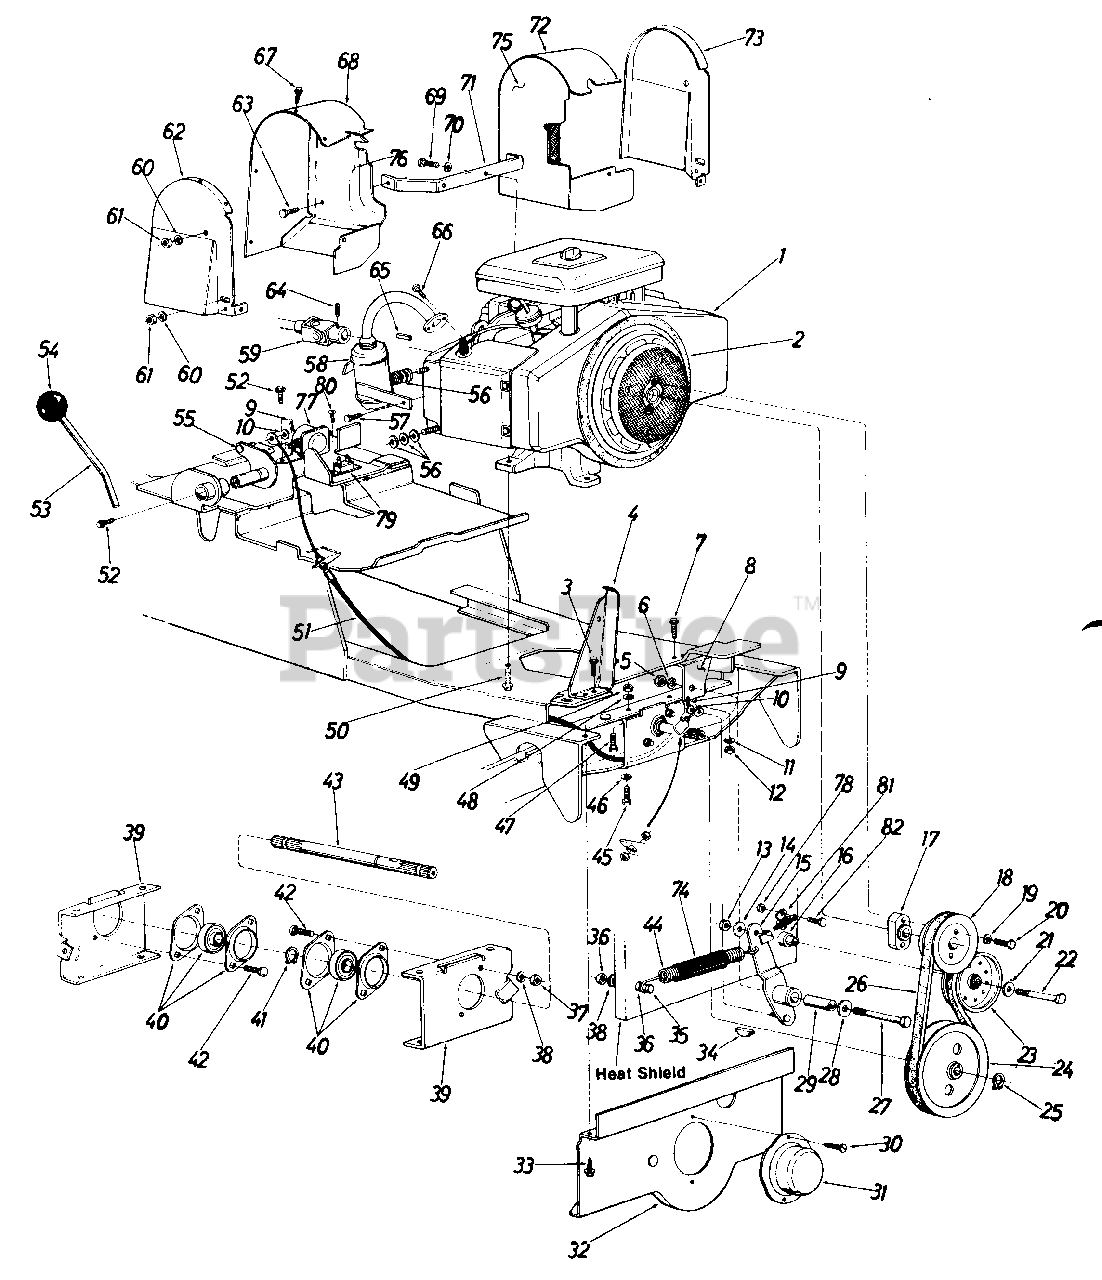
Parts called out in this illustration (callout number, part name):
1	Engine
2	Mylar Foam Strip
3	Hex Wash. Hd. Self-Tap Scr. 1/4-20 x .75" Lg.
6	L-Wash. 3/8" Scr.*
7	Hex Wash. Hd. Self-Tap Scr. 5/16-18 x .75" Lg.
10	Fl-Wash. .38" I.D x 1.25 O.D. x .10 Thk.
11	L-Wash. 3/8" Scr.
12	Hex Nut 3/8-16 Thd.
13	Hex Nut 3/8-16 Thd.*
14	Fl-Wash. .38 I.D. x 1.25" O.D. x .10 Thk.
17	Pulley Spacer
18	1/2" V-Pulley 4.75" O.D.
19	L-Wash. 3/8" Scr. H.D.
20	Hex Scr. 3/8-16 x 2.00" Lg.
21	Fl-Wash. .38" I.D. x 1.25 O.D x .010 Thk.
22	Hex Scr. 3/8-16 x 2.50" Lg.
23	Flat Idler Pulley
24	1/2" V-Pulley 7.00" O.D.
25	Snap Ring
26	"V"-Belt 1/2" x 41" Lg.
27	Hex Scr. 3/8-16 x 2.50" Lg.
28	Fl-Wash. .38" I.D. x 1.25" O.D. x .010
29	Spacer.375" I.D. x .62" O.D. x 1.830 Lg.
30	Hex "B" Tap Scr. #10 x .50" Lg.
34	#91 Hi-Pro Key
35	Hex Scr. 5/16-18 x 1.25" Lg.
36	Hex Nut 5/16-18 Thd.
37	Hex Nut 5/16-18 Thd.
38	L-Wash. 5/16" Scr.*
39	PTO Brg. Retainer Brkt.
40	1.00" Dia. Brg. w/Flangette
41	Snap Ring
42	Carr. Bolt 5/16-18 x .75" Lg.
43	Spline Shaft
44	Extension Spring
45	Hex Scr. 3/8-16 x 1.00" Lg.
46	L-Wash. 3/8" Scr.
47	Hex Scr. 3/8-16 x 1.00" Lg.
48	L-Wash. 3/8" Scr.*
49	Hex Nut 3/8-16 Thd.*
50	Hex Wash. Hd. Self-Tap Scr. 3/8-16 x 1.25" Lg.
51	PTO Control Cable
52	Hex Wash. Hd. Self-Tap Scr. 1/4-20 x .501"
53	PTO Handle
54	Ball Knob
55	PTO Actuator Lever Ass'y.
56	Fl-Wash. .312" I.D. x 1.620" O.D. x .060
57	Hex Wash. Hd. Self-Tap Scr. 1/4-20 x .50" Lg.
58	Muffler Ass'y. Comp.-R. H.
59	Universal Joint Ass'y. Comp.
60	Fl-Wash. .312" I.D. x .630" O.D. x .063
61	Hex Nut 5/16-18 Thd.
62	Shroud Outer-R.H.
63	Hex Wash. Hd. Self-Tap Scr. 1/4-20 x .50" Lg.
64	Sq. Hd. Set Scr. 5/16-18 x .38" Lg.
65	Sq. Key 1/4" x 2.00" Lg.
66	Hex Wash. Hd. Scr. 1/4-20 x 5/8" Lg.-Grade 5
67	Hex "AB" Tap Scr. #10 x .50" Lg.
68	Shroud Cover-R.H.
69	Hex Scr. 5/16-24 x .75" Lg.
70	L-Wash. 5/16" Scr.
71	Shroud Support Brkt.
72	Shroud Cover-L.H.
73	Shroud Outer-L.H.
74	Spring Cover Tubing
75	Shroud Inner Ass'y.-L.H.
76	Shroud Inner Ass'y.-R.H.
77	Solenoid
78	Hex Scr. 1/4-20 x 1/2" Lg.
79	Circuit Breaker
80	Truss Mach. Scr. #10 x .50" Lg.
81	Safety Switch
82	L-Wash. 1/4" Scr.*
